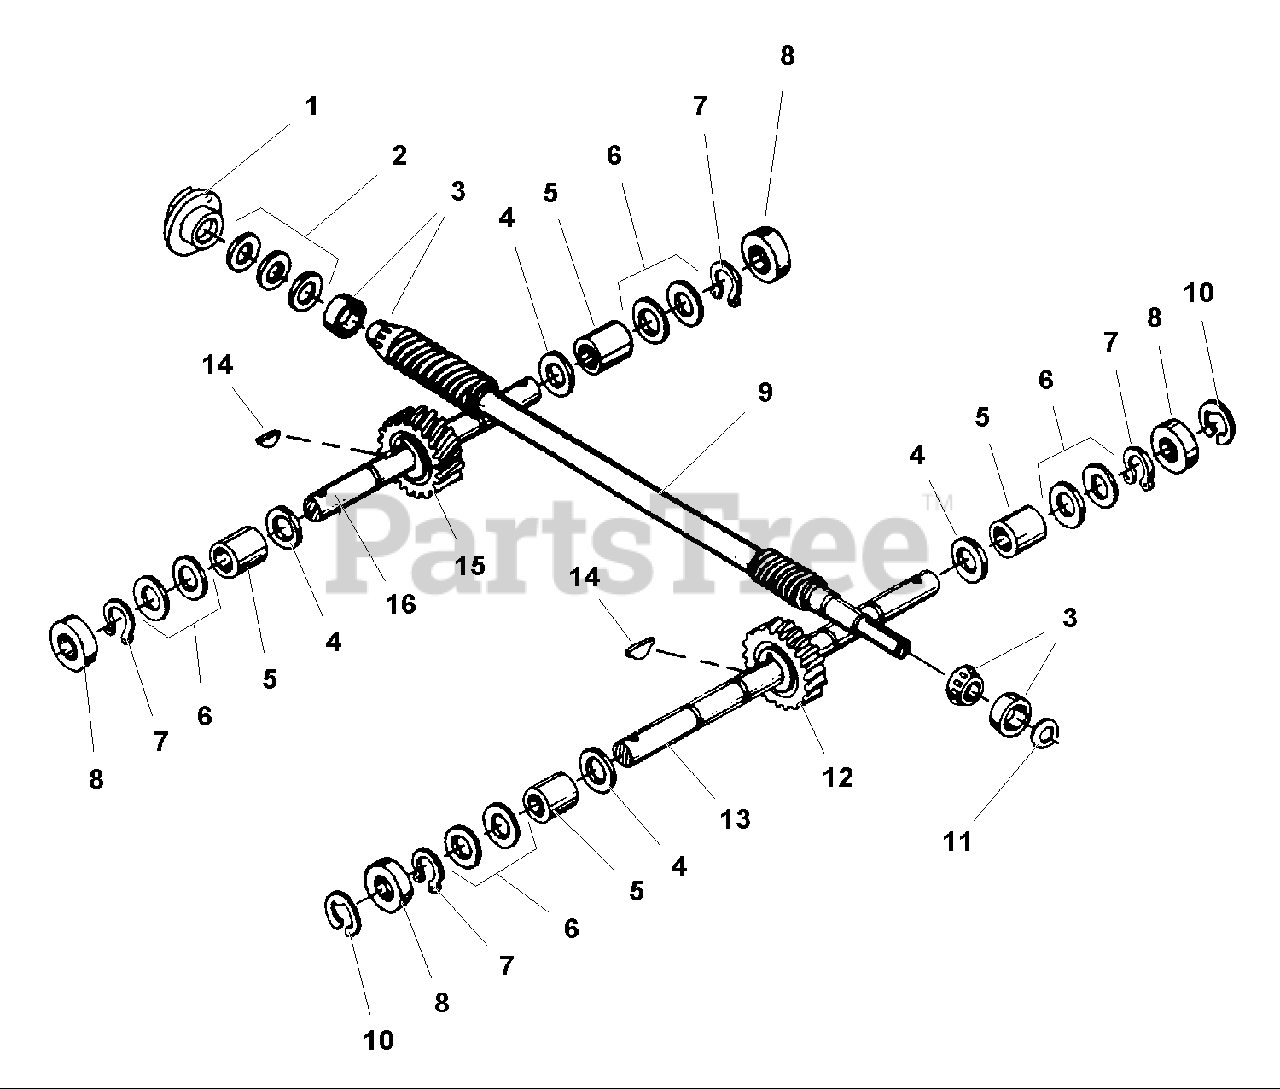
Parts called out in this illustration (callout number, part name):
1	CAP, Rear Bearing
2	SHIM SET, Rear Bearing Cap
2	SHIM, 0.062 Thickness x 1 3/4" (As Required)
2	SHIM, 0.030 Thickness x 1 3/4" (As Required)
2	SHIM, 0.015 Thickness x 1 3/4" (As Required)
2	SHIM, 0.010 Thickness x 1 3/4" (As Required)
3	BEARING, Tappered ( Cone & Race )
4	SPACER, 1" x 1 1/4" x 0.062 Thickness
6	SHIM SET, Axle Spacer
6	SHIM, 0.062 Thickness x 1 3/8"
6	SHIM, 0.030 Thickness x 1 3/8"
6	SHIM, 0.015 Thickness x 1 3/8"
6	SHIM, 0.010 Thickness x 1 3/8"
7	RING, Snap Internal Retainer
8	SEAL, Housing
9	SHAFT, Main Drive
10	RING, Snap External Retainer
11	SEAL, Oil Drive Shaft
12	GEAR, Worm Wheel Shaft
13	SHAFT ASSEMBLY, Wheel w/Lock Pin 5HP
14	KEY, Parrallel Pin
15	GEAR, Worm Shaft
16	SHAFT ASSEMBLY
